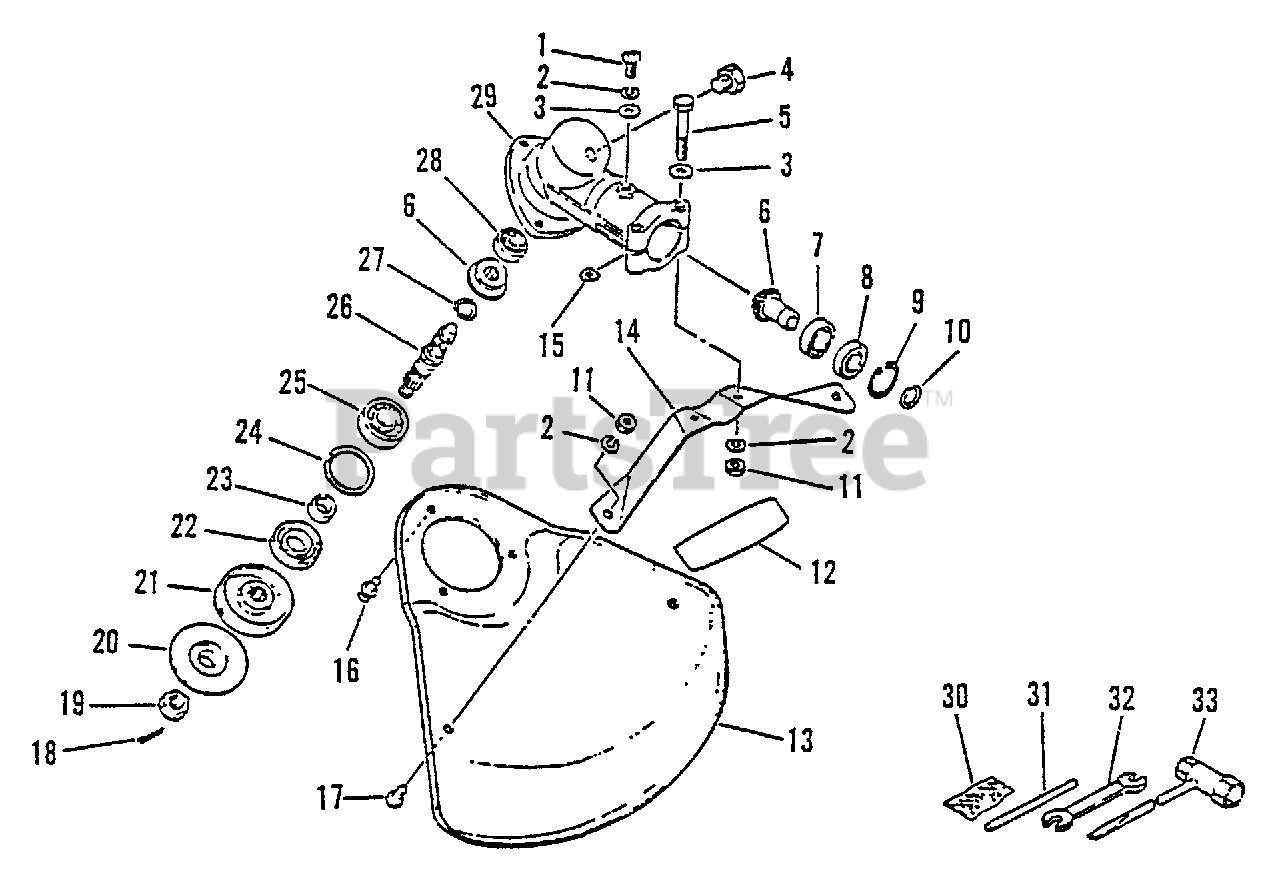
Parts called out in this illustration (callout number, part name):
1	SCREW 5×10
2	WASHER, SPRING 5
3	WASHER, FLAT 5.5×10×0.8
4	BOLT 8×8 SP
5	BOLT 5×35 SP
6	GEAR SET
7	BEARING, BALL 6900
8	BEARING, BALL 6900Z
9	RING, SNAP Ø22
10	RING, SNAP Ø12
11	NUT M5
12	LABEL, CAUTION
13	DEBRIS SHIELD KIT
14	BRACKET, SHIELD MOUNTING
16	SCREW 5×10
17	SCREW 5×8
18	PIN, COTTER 2×22
20	PLATE, ADAPTOR - LOWER
21	PLATE, ADAPTER - UPPER
22	SEAL, OIL 22
23	SPACER 11.8×15×9
24	RING, SNAP Ø32
25	BEARING, BALL - 6201 C3
26	SHAFT, GEAR
27	RING, SNAP Ø10
28	BEARING, BALL 609
29	HOUSING, GEAR CASE
30	PIN, COTTER 2×22 (PKG. OF 10)
31	TOOL, LOCKING 5×120 MM
32	SPANNER 8×10
33	T-WRENCH 17x-19 L200
